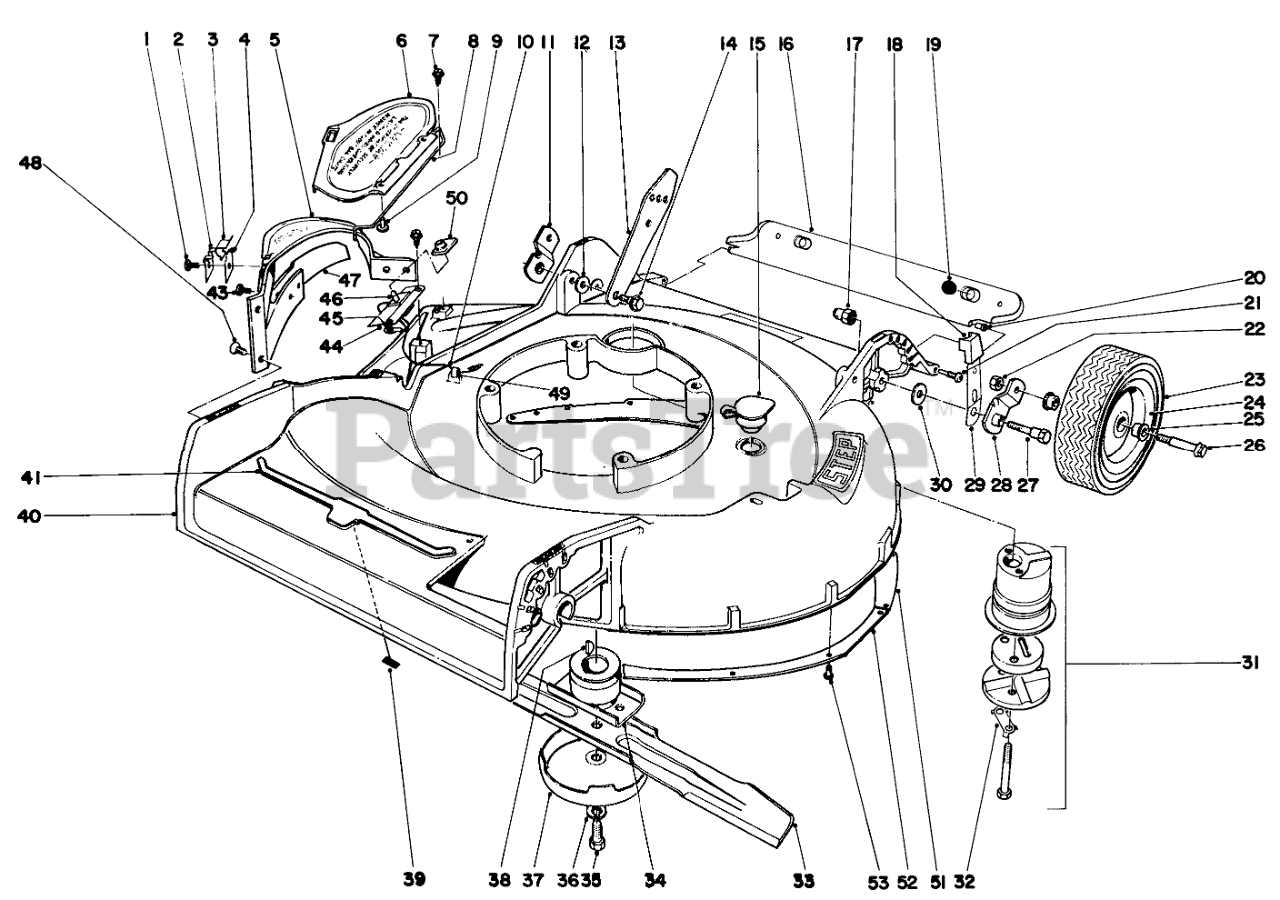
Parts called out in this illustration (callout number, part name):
2	Lower Clip
3	Upper Clip
4	Wear Plate
5	Deflector
6	Deflector (Incl.Ref. #8 & #9)
7	SCREW-HWHTF
8	Hinge Pin
9	Rivet
10	Lead Wire
11	Pivot Arm
12	SPACER
13	Handle Latch
14	SCREW-SHOULDER
15	WASHOUT PLUG
16	Safety Shield (IncI. #19 & #20)
17	Nut
18	Knob
19	SKID BUTTON
20	SAFTEY SHIELD BUSHING
21	SAFTEY SHIELD SCREW
22	Nut
23	8 TIRE
24	Wheel (Incl.Ref. #25)
25	FLANGE BUSHING
27	5/16-18 PIVOT SCREW
28	Pivot Arm
29	Spring Arm
30	WASHER-PIVOT
31	Muffler
32	CLIP - LOCKING
33	Blade
34	BLADE RETAINER WA
35	SPECIAL SCREW
36	WASHER-LOCK
37	AntiScalp Cup
38	KEY-WOODRUFF
40	Housing (Incl.Ref. #51-#53)
41	Emblem, Bullshead
44	Mounting Plate
45	Ground Wire
46	Switch
47	DefIector Bar
48	Screw
50	Boot Switch
51	Main Skirt
52	Secondary Skirt
